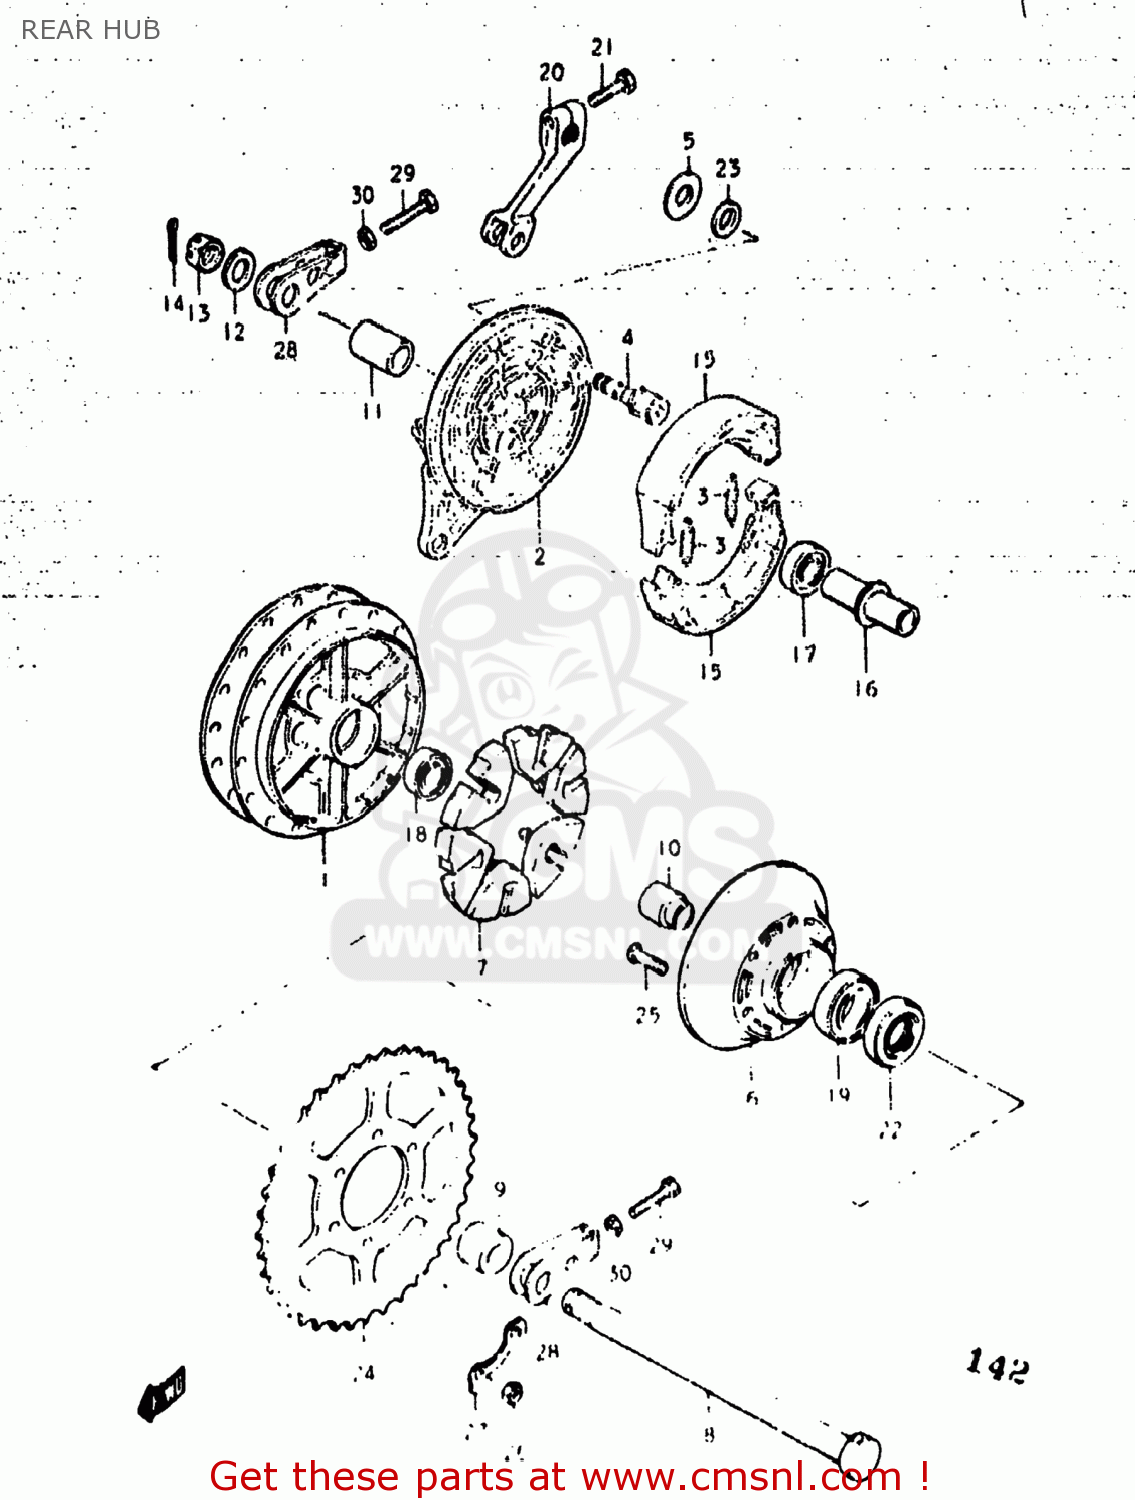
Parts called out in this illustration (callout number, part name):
1	DRUM,REAR HUB
2	PANEL,REAR HUB
3	SPRING,BRAKE SHOE
4	CAM,FRONT BRAKE
5	WASHER (15X24X1.6)
6	DRUM,REAR SPROCKET MOUNT
7	CUSHION,REAR DRUM
8	AXLE,REAR
9	SPACER(17X30.5X22.3)
10	SPACER,REAR HUB BEARING
11	SPACER(17.5X28X44.8)
12	WASHER
13	NUT
14	PIN, COTTER
15	SHOE SET,BRAKE (MCA)
16	SPACER
17	BALL BEARING
18	BEARING
19	BEARING
20	LEVER,REAR BRAKE CAM
21	BOLT
22	OIL SEAL
23	O-RING,BOSS
24	SPROCKET,RR
25	BOLT
26	NUT
27	WASHER
28	ADJUSTER,CHAIN
29	BOLT
30	NUT
